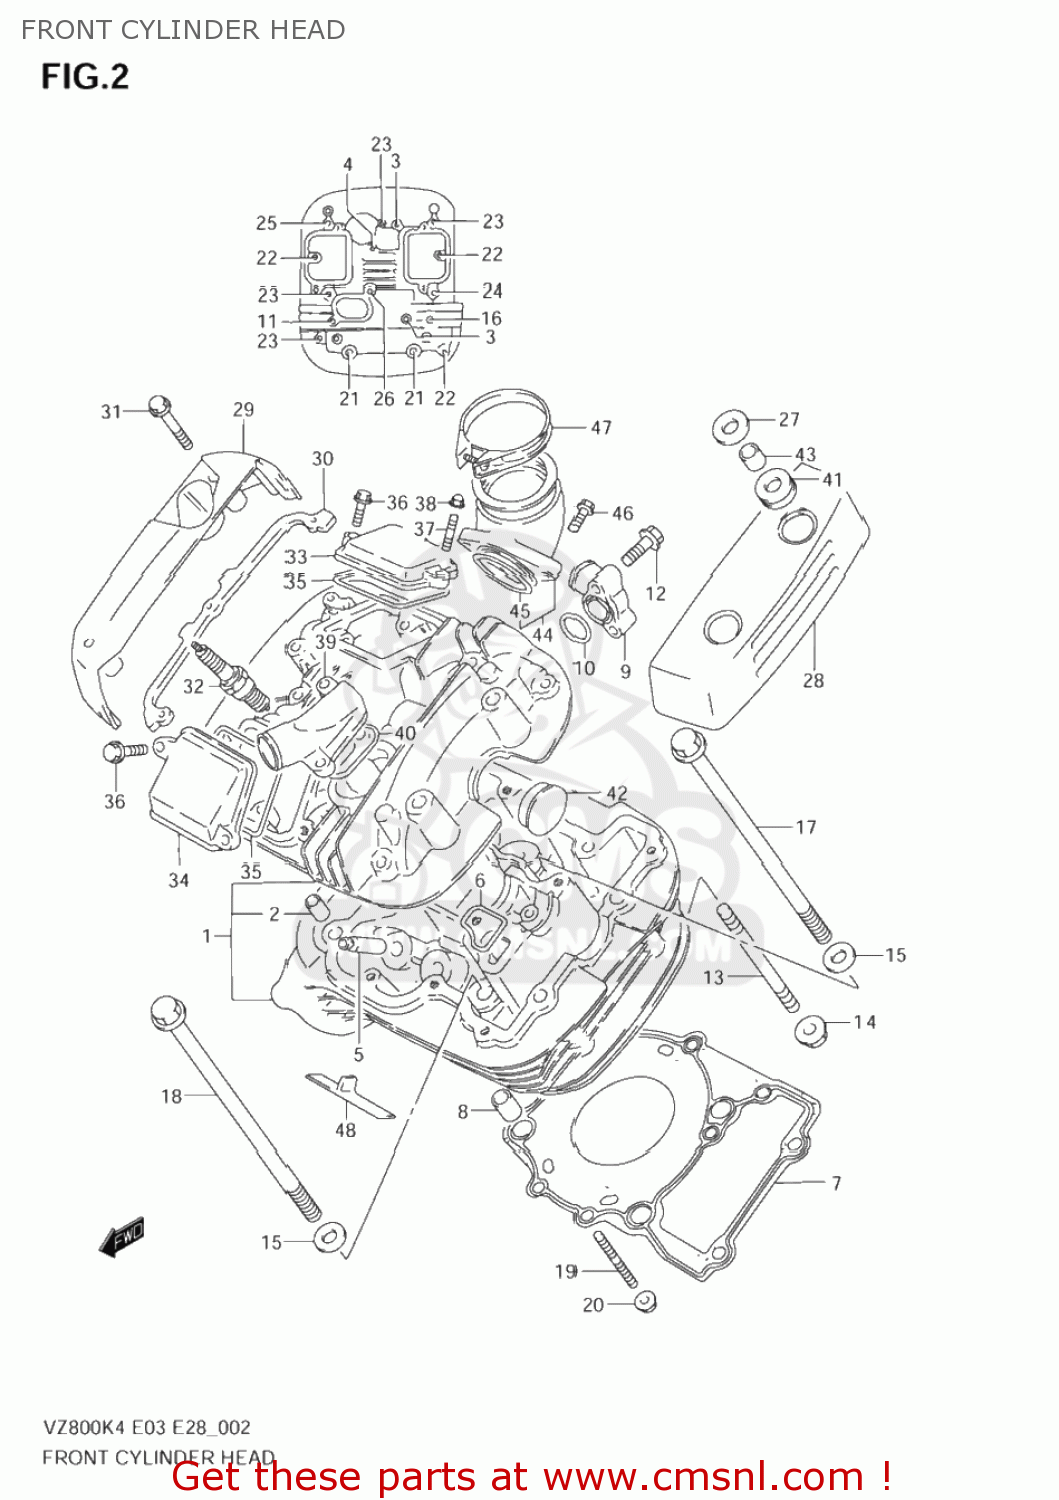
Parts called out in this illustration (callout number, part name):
1	HEAD ASSY,CYLINDER FR
2	PIN(8.4X11X14)
3	BOLT(6X50)
4	BOLT(6X55)
5	GUIDE,VALVE
6	GASKET,CYLINDER HEAD WATER (NAS)
7	GASKET,CYLINDER HEAD FR (NAS)
8	PIN
9	UNION,CYLINDER HEAD WATER
10	O RING(D:2.4,ID:17.8)
11	BOLT
12	SCREW
13	BOLT,STUD
14	NUT
15	WASHER(10.5X22X2.3)
16	BOLT(8X140)
17	BOLT(10X155)
18	BOLT(10X165)
19	STUD BOLT
20	NUT
21	BOLT(8X245)
22	BOLT
23	BOLT
24	BOLT
25	BOLT
26	BOLT(6X55)
27	WASHER(8.5X24X1.6)
28	CAP,CYL HEAD COVER,FL & RR
29	CAP,CYLINDER HEAD COVER,F-R
30	CUSHION,FR,R CAP
31	BOLT(6X40)
32	SPARK PLUG X22E
33	CAP,INSPECTION INTAKE
34	CAP,INSPECTION EXHAUST
35	GASKET,INSPECTION CAP (NAS)
36	SCREW
37	BOLT,STUD
38	NUT
39	UNION,WATER OUTLET
40	GASKET,WATER OUTLET UNION (NAS)
41	CUSHION
42	PLUG(OD:30)
43	BUSH
44	PIPE ASSY,INTAKE FR
45	O RING(D:2.4,ID:39.7)
46	SCREW
47	CLAMP
48	PLATE,HEAD COVER RR
